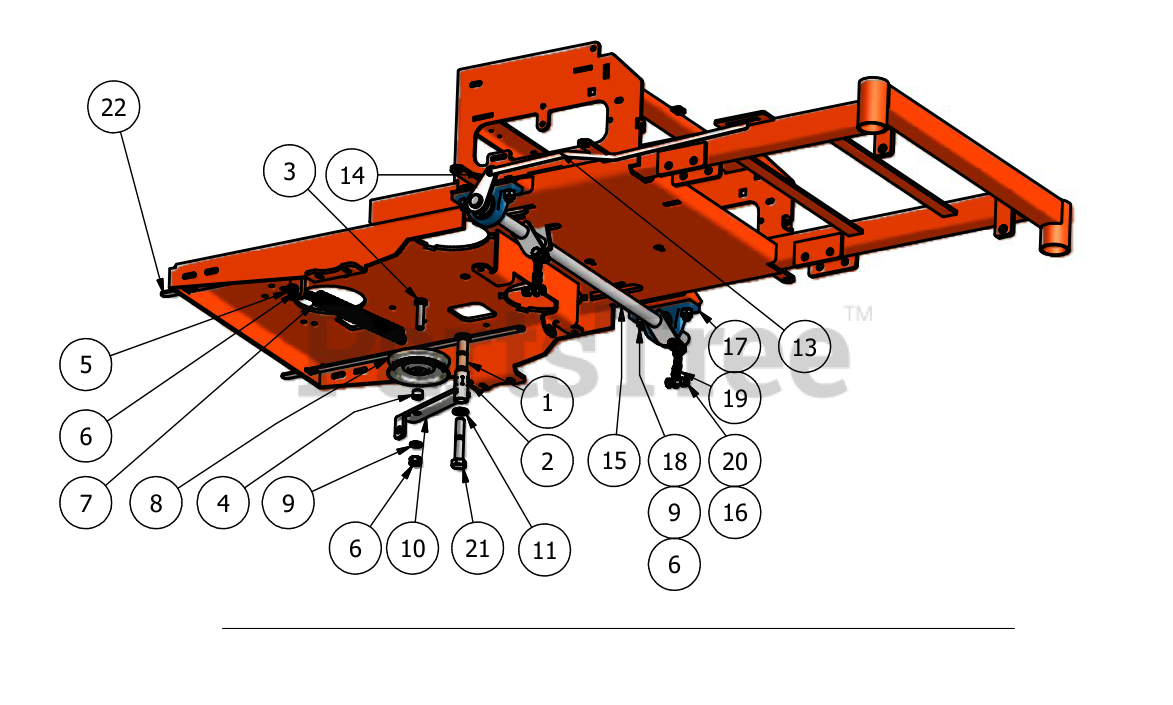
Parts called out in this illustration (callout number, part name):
1	Bronze Bushing
2	Grease Fitting
3	1/2" x 2" Bolt
4	1/2" Spacer
5	Spring Tensioner
6	1/2" Hex Nut
7	Pump Idler Spring
8	4 3/4" Idler Pulley
9	1/2" Lock Washer
10	Pump Idler Bracket
11	5/8" Nylon Washer
12	5/8" Nylock Nut
13	Height Indicator Bar
14	Height Indicator Lever
15	Actuator Bar - Transaxle
16	3/8" Nylock Nut
17	Pillow Block Bearing
18	1/2" x 1 1/2" Hex Bolt
19	Deck Chain
20	3/8" x 1 1/2" Bolt
21	5/8" x 4" Hex Bolt
22	Transaxle Neutral Lever
